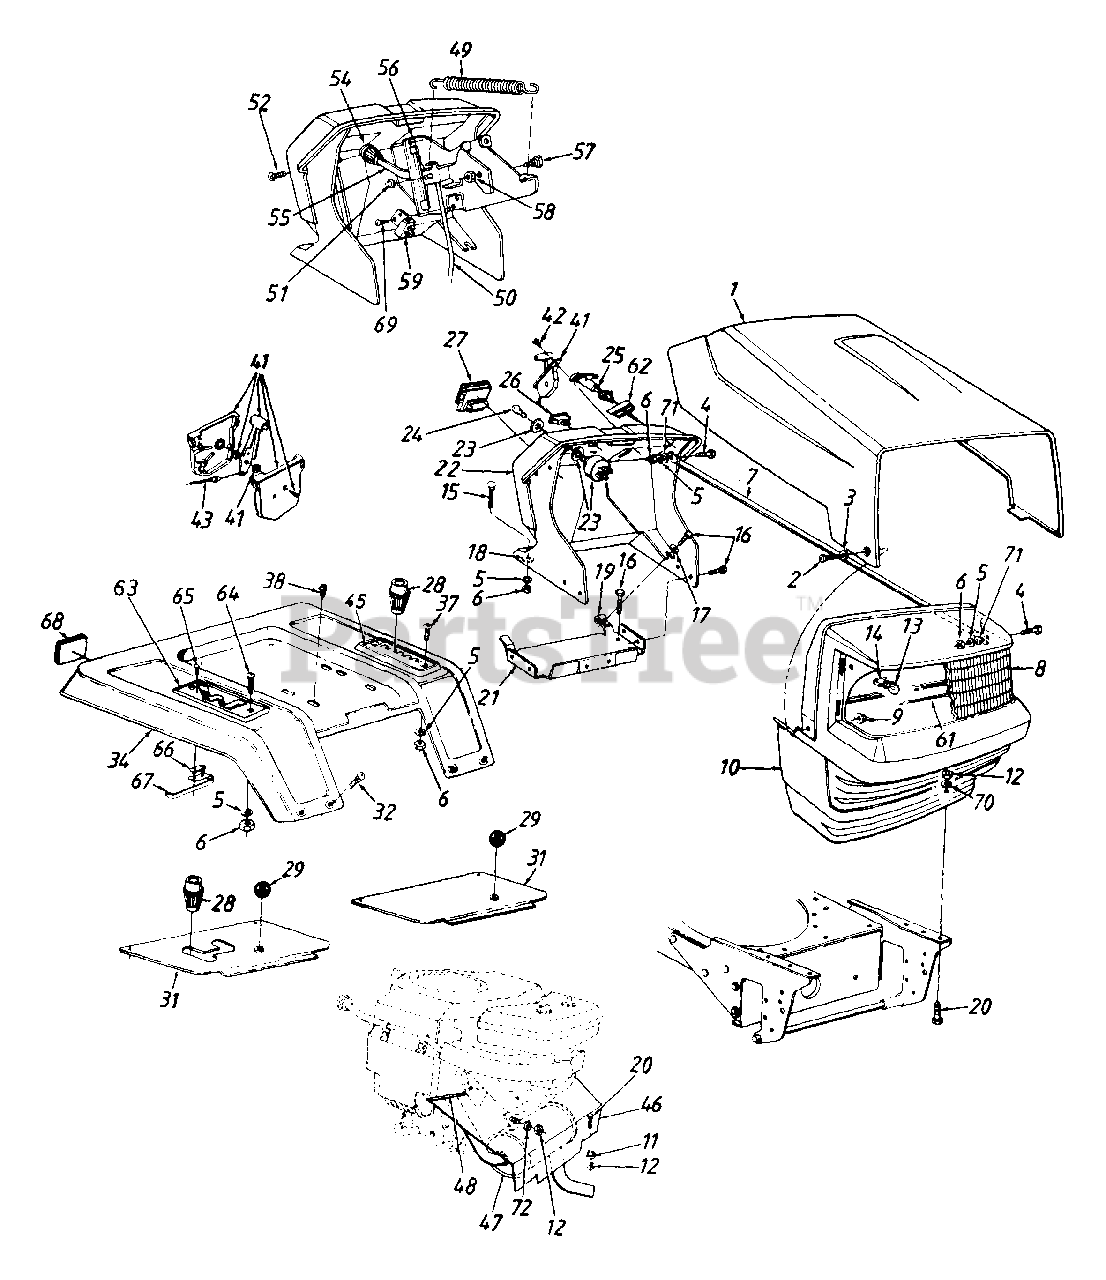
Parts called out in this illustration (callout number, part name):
3	Spr. Wash..265" I.D. x .562" O.D.
4	Hex Bolt 1/4-20 x .62" Lg.
5	L-Wash. 1/4" I.D.
6	Hex Nut 1/4-20 Thd.
7	Grille Support Rod
8	Headlight Lens
9	Flange L-Nut 1/4-28 Thd.
10	Grille
11	L-Wash. 5/16" I.D.
12	Hex Nut 5/16-18 Thd.
13	Lamp
14	Socket
15	Carriage Bolt 1/4-20 x 1.0" Lg.
16	Hex AB-Tap Scr. 1/4 x .62" Lg.
17	Fl-Wash..281" I.D. x .73" O.D.
18	Bolt Retainer 1/4" I.D.
19	Speed Nut 1/4-20 Thd.
20	Hex Bolt 5/16-18 x .75" Lg.
23	Ignition Switch
24	Ignition Key
25	Choke Control
26	Light Switch
27	Ammeter
28	Shift Knob
31	Shift Cover
32	Carriage Bolt 1/4-20 x .5" Lg.
38	Hex Wash. Hd. AB-Tap Scr. 5/16 x .75" Lg.
41	Throttle Box Ass'y.
42	Truss Mach. AB-Tap Scr. 010 x .5" Lg.
43	Throttle Control Wire
45	6-Speed Selector Plate
46	Front Heat Shield
47	Muffler
48	Trim Strip 12" Lg.
49	Ext. Spring 5.06" Lg.
50	Deck Control Rod
51	Speed Nut 1/4" Rod
52	Torx Mach. Scr. 1/4 x .62" Lg.
54	PTO Knob
55	PTO Lever
56	PTO Bracket
57	Shld. Bolt .437" Dia. x .162"
58	Hex L-Nut 5/16-18 Thd.
59	Safety Switch (PTO)
61	Grille Reflector Label
62	Retainer Clip
63	Forward/Reverse Index Brkt.
64	Truss Mach. Scr. 1/4-20 x .75" Lg.
65	Hex Wash. Hd. AB-Tap Scr. #8 x .5" Lg.
66	Insulator Nut Plate
67	Reverse Safety Switch
68	Reflector
69	Hex Wash. Hd. 8 - Tap Scr. #10 x .38" Lg.
70	Fl-Wash..344" I.D. x 1" O.D.
71	Fl-Wash..28" I.D. x .75" O.D.
72	Spec. L-Wash. 5/16" I.D.
